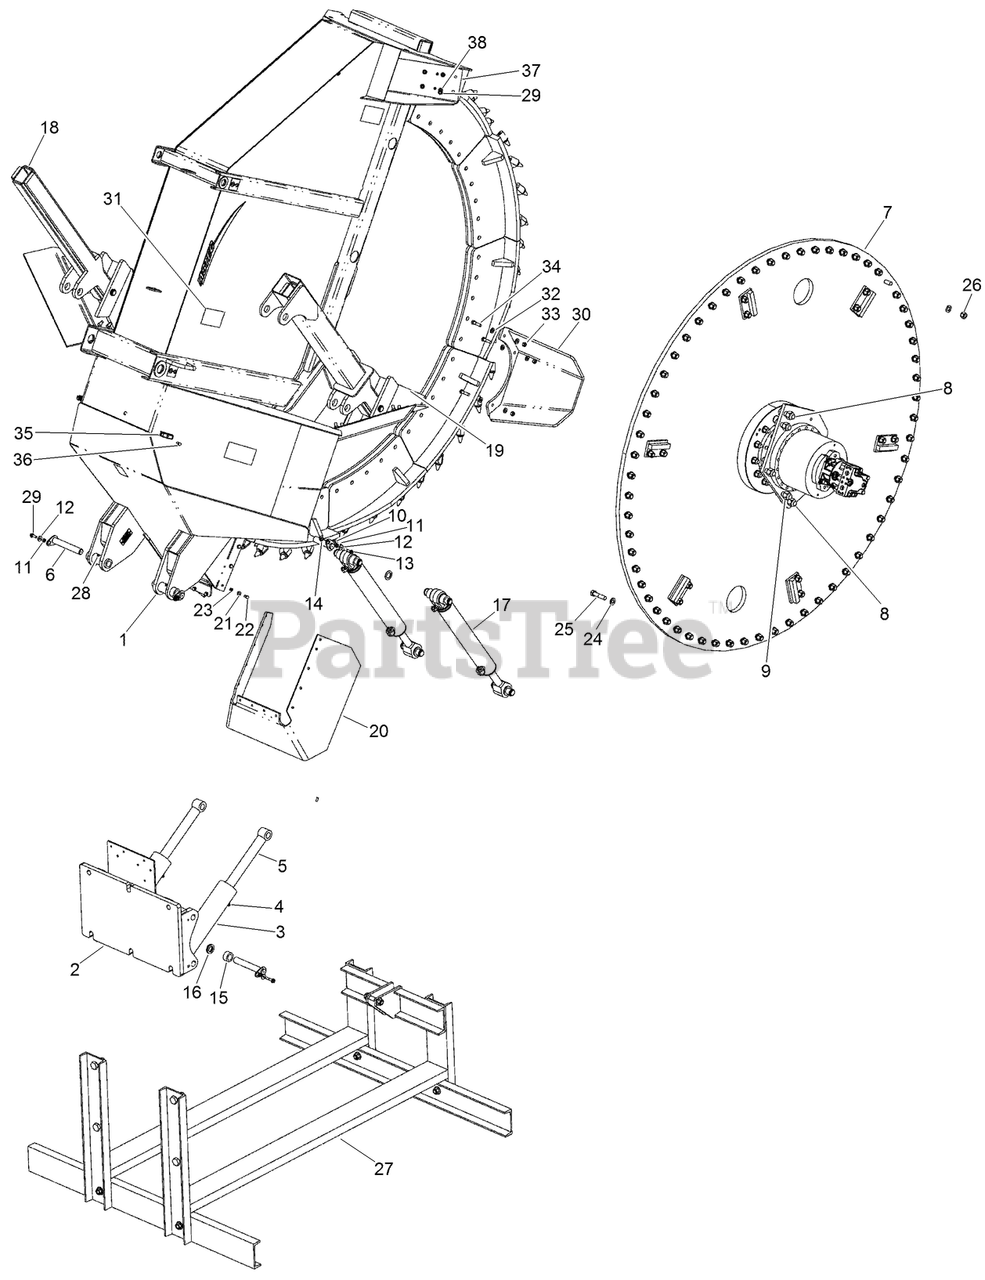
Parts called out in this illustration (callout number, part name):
1	FRAME WELDMENT - Rock Wheel
2	WELDMENT - Rock Wheel Mount
3	CYLINDER - Hydraulic, Base
4	CONNECTOR-Str Thd 3/8, 37FL-ORB 3/8
5	CYLINDER - Hydraulic, Base
6	PIN-PIVOT W/ FLAG
7	WHEEL ASSEMBLY - Motor/Disc/Hardware
10	PIN - Pivot with Flag
13	SCREW-FLANGE
14	NUT-FLANGE, NYLOCK
15	SPACER - Pin
17	STABILIZER GROUP - Rock Saw
18	ASSEMBLY - Stabilizer, RH
19	ASSEMBLY - Stabilizer, LH
20	SKIRT - Rock Wheel
21	WASHER-0.406 x 0.812 x 0.065 in CST ZND
22	BOLT-hex, 3/8 NC x 1-1/2 inch
23	NUT
25	BOLT - Hex Hd .75 x 3.25 GR8 ZND
26	NUT-Prev Trq 3/4 GRC CAD Direct
27	STAND - 46 Rocksaw
28	FITTING-Lube 1/8-27 Dryseal PTF
29	SCREW-HH
30	WELDMENT - Motor Guard
31	DECAL GROUP - 46 Rock Saw
32	WASHER-FLAT
33	NUT-LOCK, HEX
35	CLAMP-TUBE
36	BOLT - Hex Hd .375 x 1.375 GR8 ZND
37	PLATE - Adjustable Ejection
38	NUT, METRIC HEX FLANGE - M10, Zinc
